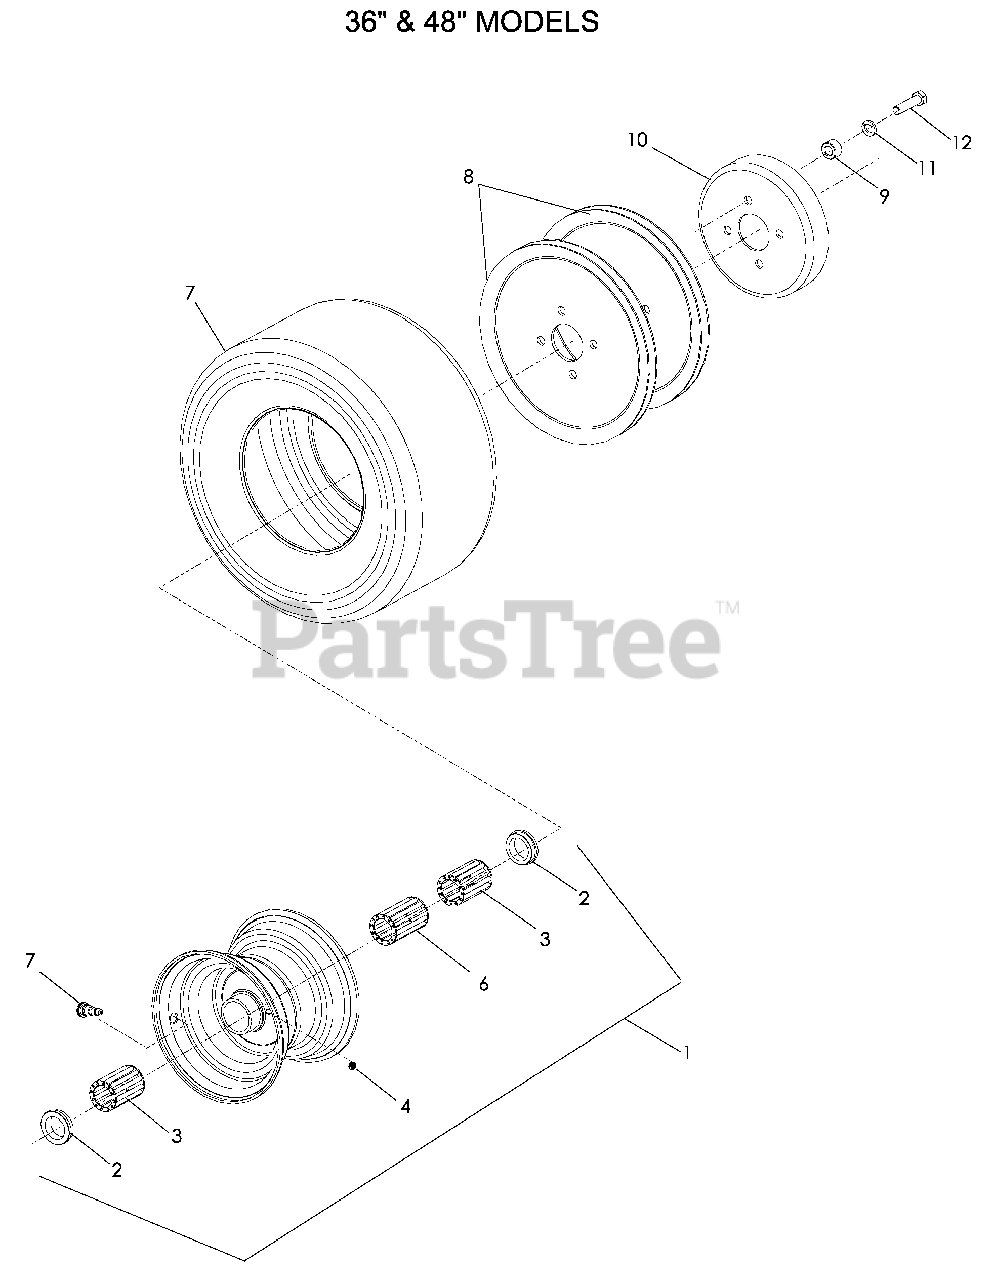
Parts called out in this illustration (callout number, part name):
1	WHEEL ASSM
3	ROLLER BEARING(SHORT)
4	ZERK ¼-28 STRAIGHT
5	ROLLER BEARING(LONG)
7	TRACTION PULLEY
9	BRAKE DRUM
10	LOCKWASHER 3/8
11	HCS 3/8-24 x 1½
